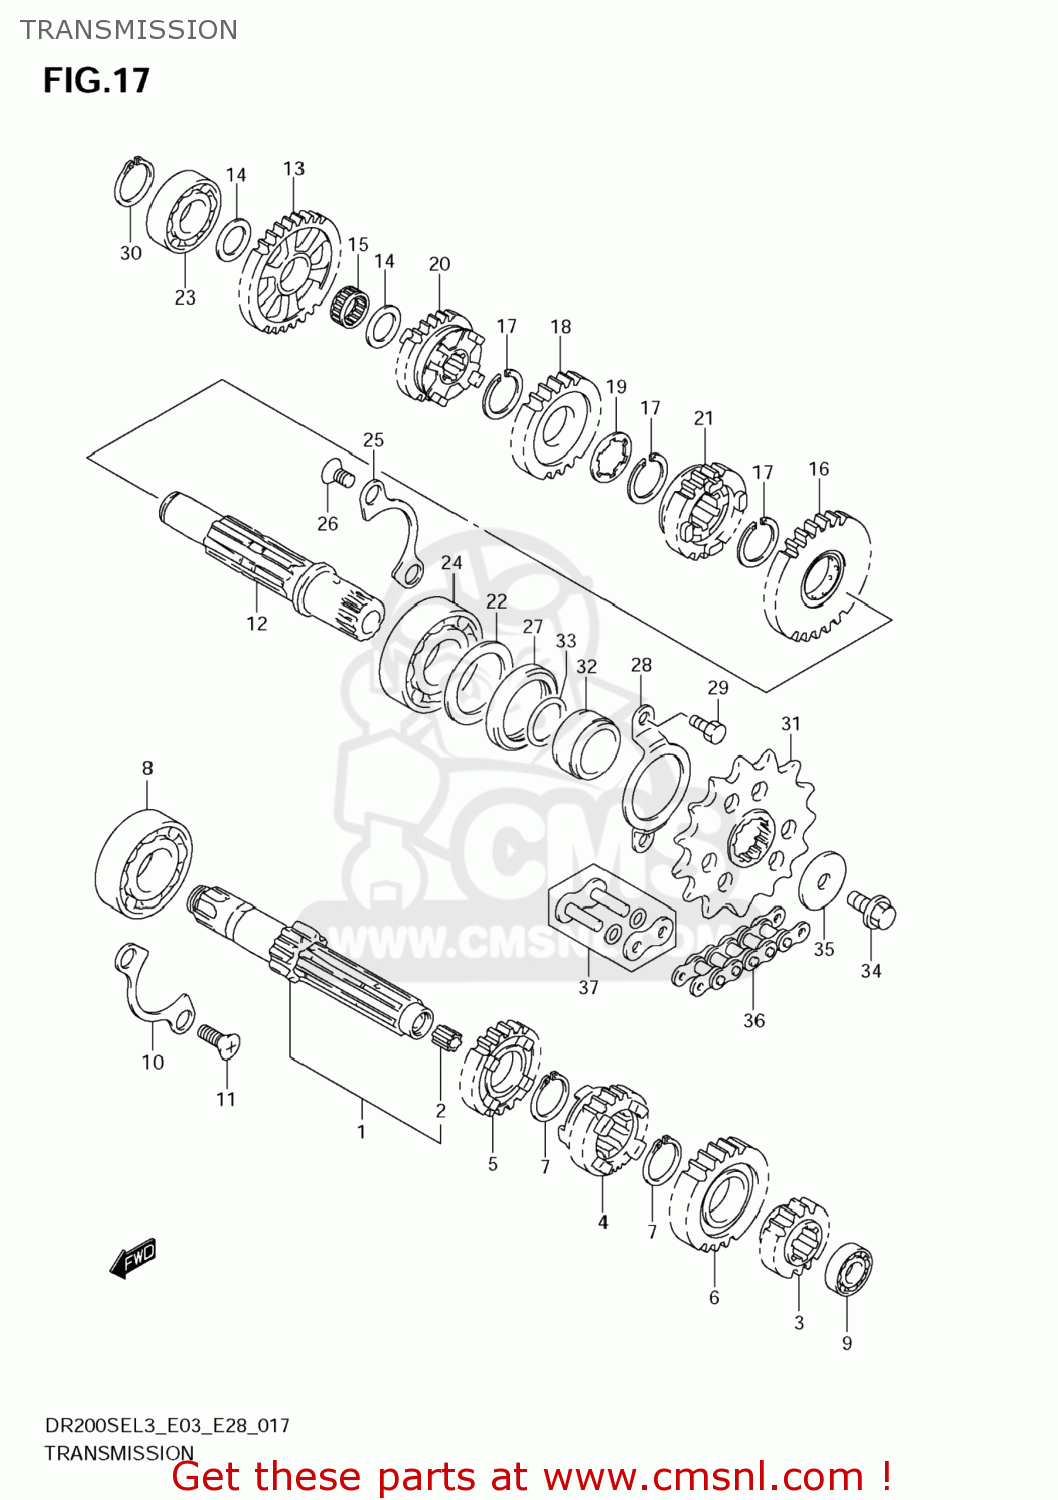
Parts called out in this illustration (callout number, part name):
1	SHAFT,COUNTER
2	BUSH
3	GEAR,2ND DRIVE
4	GEAR,3RD DRIVE(NT:16)
5	GEAR,4TH DRIVE
6	GEAR,5TH DRIVE(NT:23)
7	CIRCLIP
8	BEARING(20X47X14)
9	BEARING
10	RETAINER,DRIVE SHAFT BEARING
11	SCREW(6X12)
12	SHAFT,DRIVE
13	GEAR,1ST DRIVEN
14	SHIM(17X26X1)
15	BEARING(17X21X9.8)
16	GEAR,2ND DRIVEN(NT:29)
17	CIRCLIP
18	GEAR,3RD DRIVEN(NT:23)
19	WASHER,LOCK
20	GEAR,4TH DRIVEN(NT:23)
21	GEAR,5TH DRIVEN
22	WASHER,OIL SEALING
23	BEARING(17X36X12)
24	BEARING(22X50X14)
25	RETAINER,DRIVE SHAFT BEARING
26	SCREW(6X12)
27	SEAL,OIL(30X40X6)
28	RETAINER,DRIVE SHAFT OIL SEAL
29	BOLT
30	CIRCLIP
31	SPROCKET,ENGINE
32	SPACER,ENGINE SPROCKET
33	O RING(D:2.5,ID:21)
34	BOLT
35	WASHER
36	CHAIN(DID520VC5,112LE)
37	JOINT SET,CHAIN
